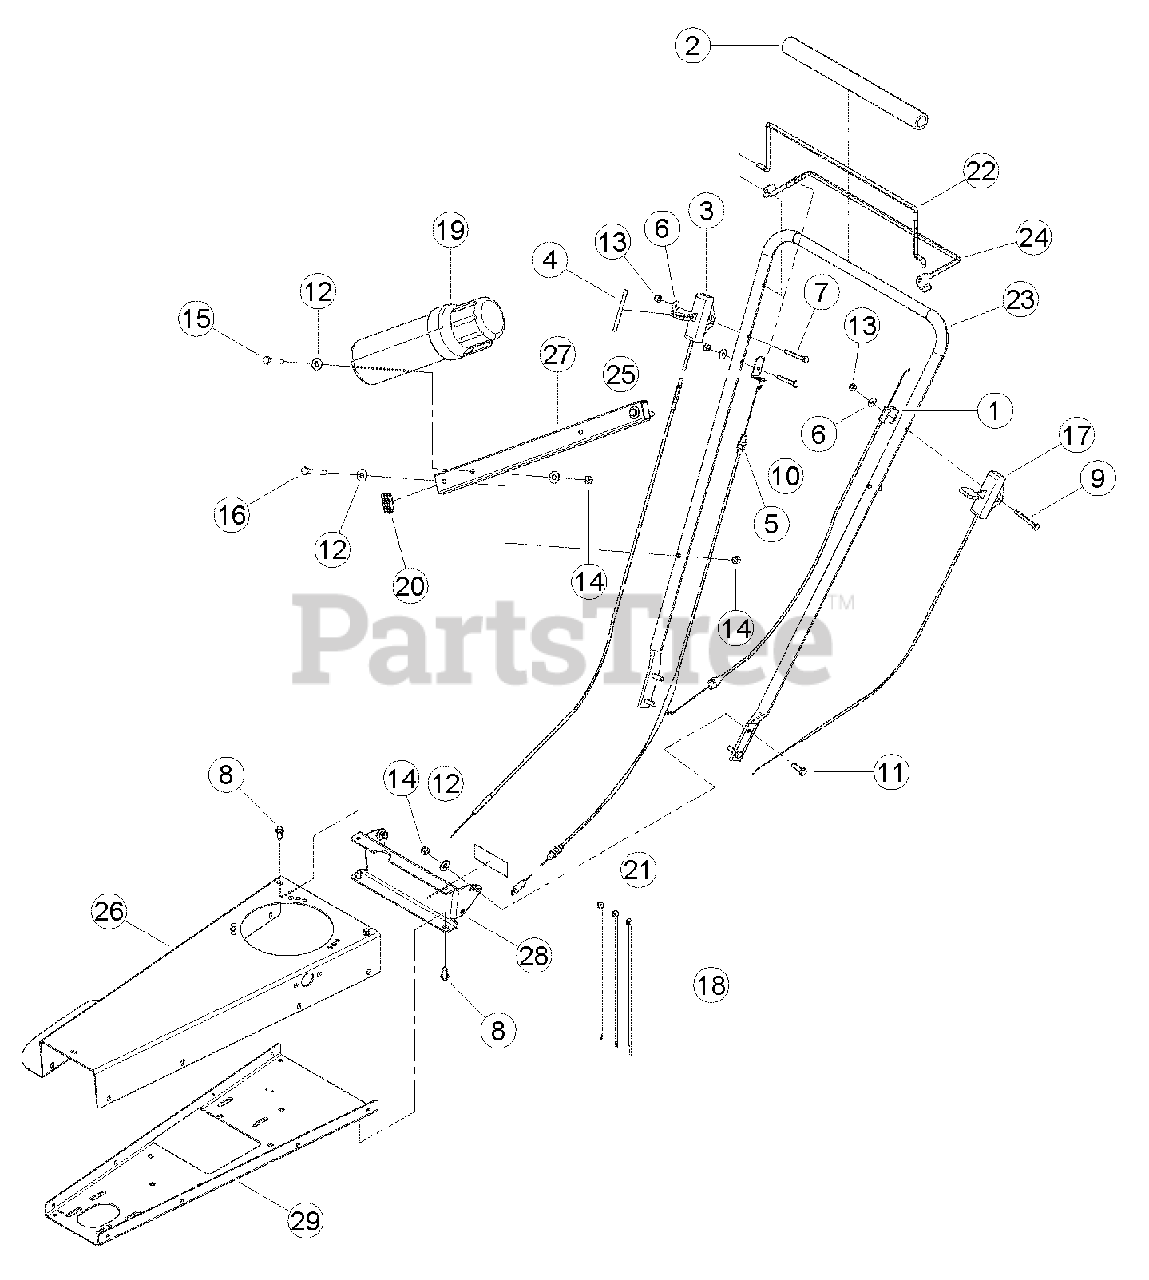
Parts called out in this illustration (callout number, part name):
1	CABLE, BRAKE CONTROL
2	PAD, FOAM HANDLEBAR
3	CABLE, TRANSMISSION CONTROL
4	DECAL, 3 SPEED
5	CABLE, SP CONTROL
6	WASHER, 1/4 FLAT ZP
7	BOLT, 1/4 X 2 HEX HD GR5 ZP (WT160S ONLY)
7	BOLT, 1/4 X 1-3/4 HHCS GR5 ZP (WT190S ONLY)
8	SCREW, 11/32 X 7/8 HWH AB THREAD ZP
9	BOLT, 1/4 X 2-1/4 HCS GR5 ZP (WT160S ONLY)
9	BOLT, 1/4 X 1-1/2 HHCS GR5 ZP (WT190S ONLY)
10	BOLT, 1/4 X 1-1/4 HEX HD GR5 ZP
11	BOLT, 5/16 X 1 HEX HD GR5 NC ZP
12	WASHER, 5/16 FLAT ZP
13	NUT, 1/4 NE NYLOCK ZP
14	NUT, 5/16 NE NYLOCK ZP
15	BOLT 5/16-18 X 1-3/4 HCS GR5 ZP
16	BOLT, 5/16 X 2-1/4 HCPS GR5
17	THROTTLE CONTROL (WT160S ONLY)
18	STRAP, 11 IN. BLACK TIE
19	CONTAINER, MANUAL
20	CAP, PLASTIC 3/4 X 1-1/2 TUBE
21	DECAL, ATLANTIC BRIDGE LTD INFO (WT190S ONLY)
22	BAIL, TRIMMER
23	HANDLEBAR, TRIMMER
24	WELDMENT, SP BAIL
25	ANCHOR, SP CABLE
26	BODY, TRIMMER
27	TUBE, CONTAINER MANUAL
28	CHANNEL, HANDLE SUPPORT
29	BOTTOM, TRIMMER FRAME
